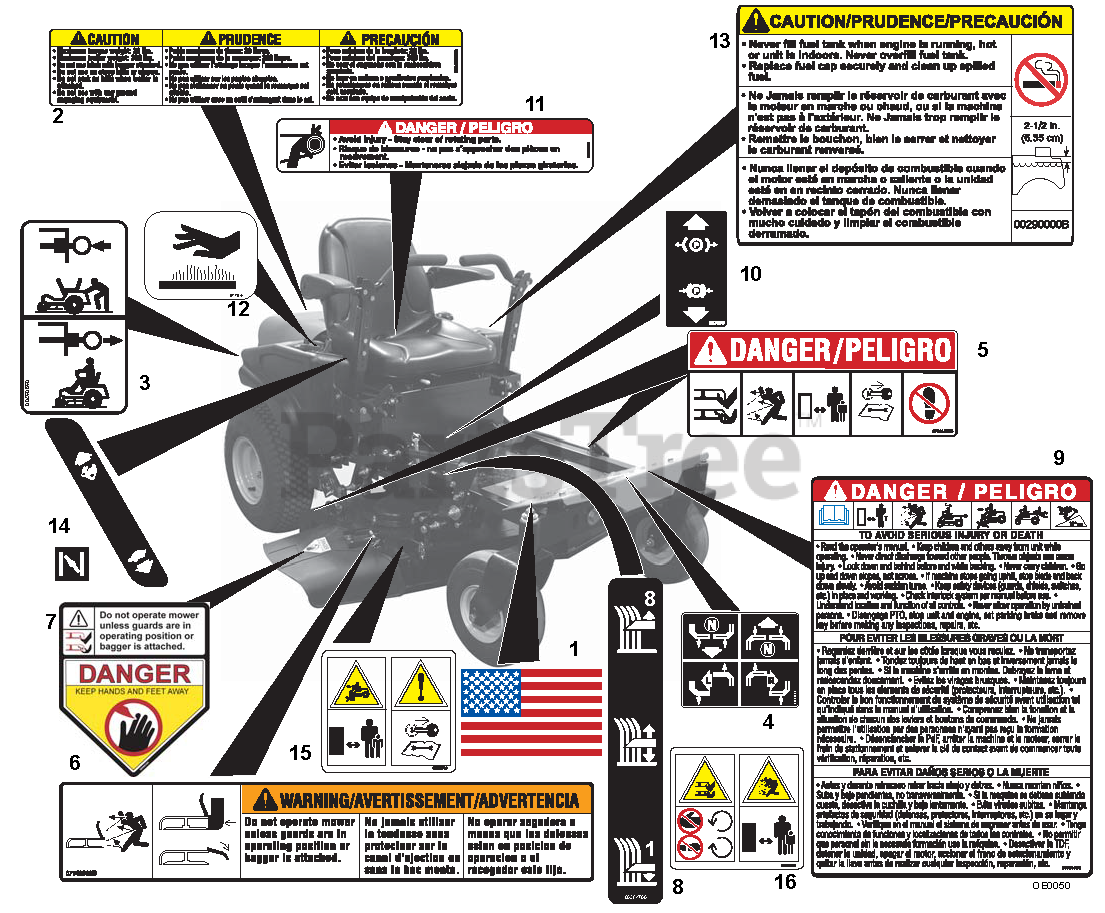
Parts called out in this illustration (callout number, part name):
1	DECAL, AMERICAN FLAG
2	DECAL, TRAILER HITCH
3	DECAL, TRANSMISSION DISCONNECT
4	DECAL, INSTRUCTIONAL-STEERING
5	DECAL, MOWER PAN DANGER
6	DECAL, WARNING
7	DECAL, CPSC DANGER
8	DECAL,CUT HEIGHT
9	DECAL, DANGER BILINGUAL
10	DECAL, PARKING BRAKE LEVER
11	DECAL- DANGER
12	DECAL, HOT SURFACE
13	DECAL,FUEL WARNING
14	DECAL, SPEED CONTROL
15	DECAL, CE CAUTION
16	DECAL, CE DECK
